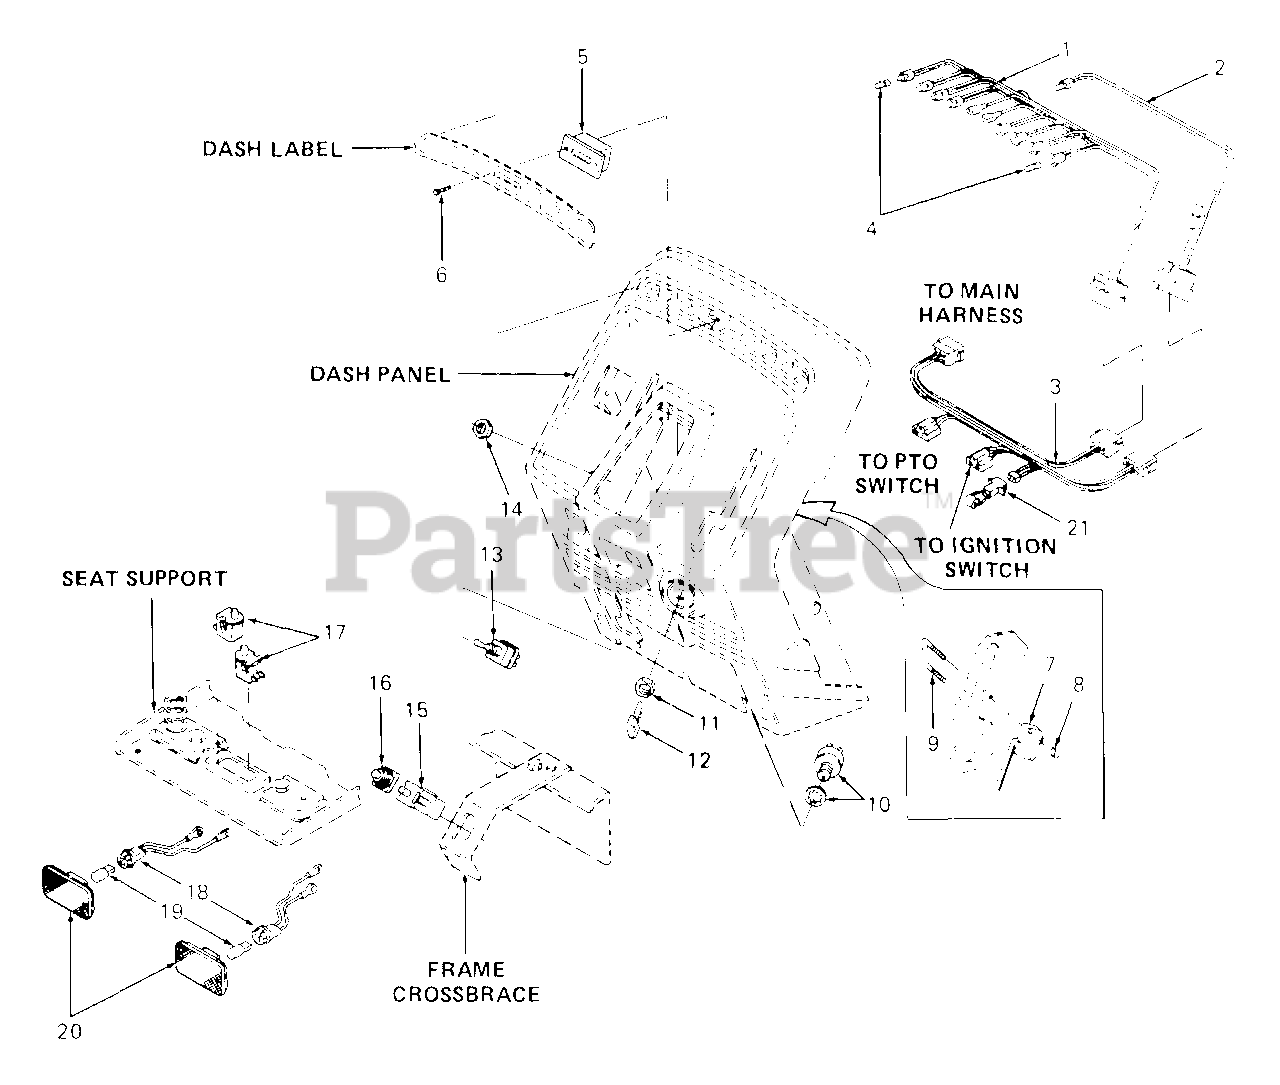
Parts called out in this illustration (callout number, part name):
1	Harness, Indicator Wire
2	Harness, Indicator Adapter
3	Harness, Pedestal
4	Bulb, Indicator
5	Hour Meter
6	Screw, Truss Hd Tapp, #6 x .62 Lg
7	Switch, Reverse
8	Nut, Hex Insert Lock, #4-40
9	Screw, Switch
10	Switch, Ignition
11	Nut, Ignition Switch
12	Key, Ignition (Set of 2)
13	Switch, PTO
14	Nut, Hex, 1/2-27 x .100 Thk
15	Switch, Interlock
16	Boot, Switch
17	Switch, Snap Mount Normally Open (Black)
18	Cable Assy, Tail Light
19	Bulb, Tail Light
20	Lens Assy, Tail Light
21	Diode Assy
